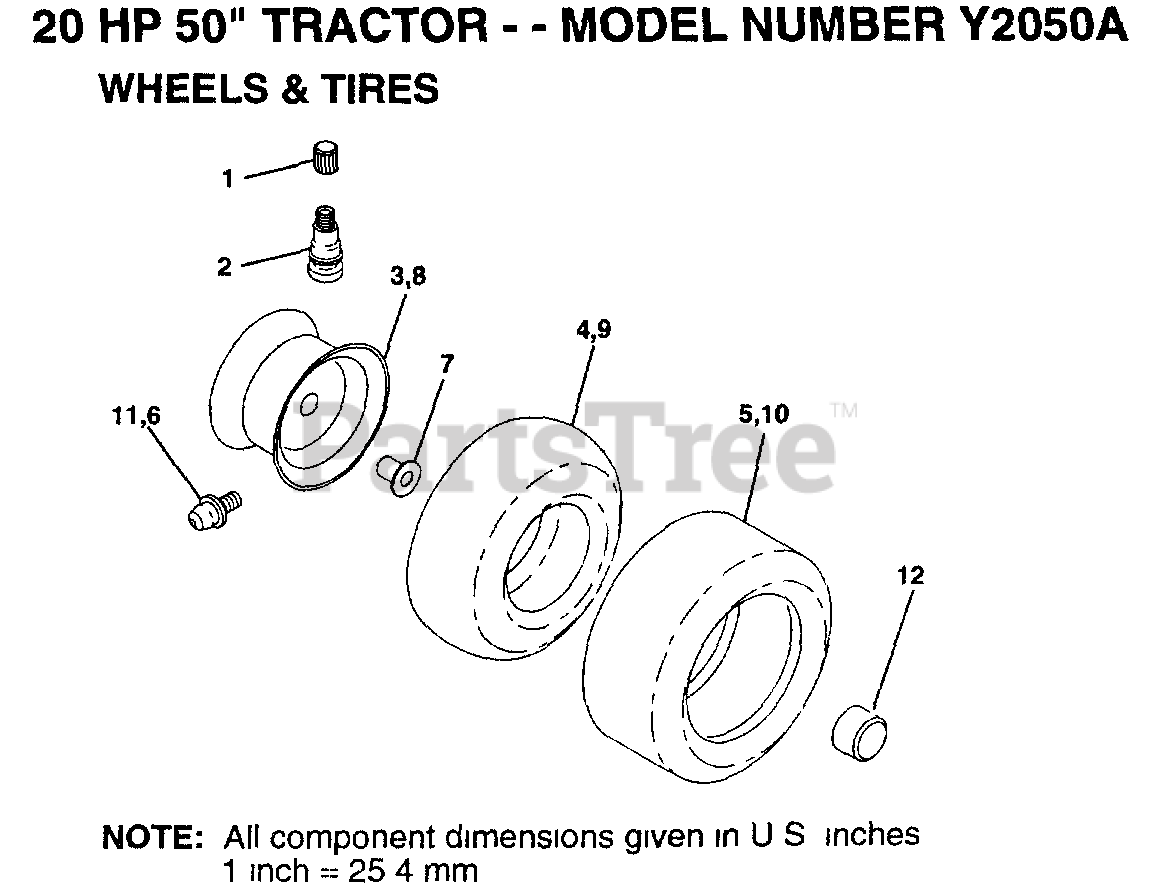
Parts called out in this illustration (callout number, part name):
1	VALVE CAP
2	VALVE STEM LT
3	RIM.FRONT.
4	TUBE.16X6.5/7.5-8
6	FITTING LT
7	"FLANGE, BEARING"
8	"WHEEL,REAR"
9	TUBE.23X8/10-12
11	ZERK FITTING M
12	HUB CAP
